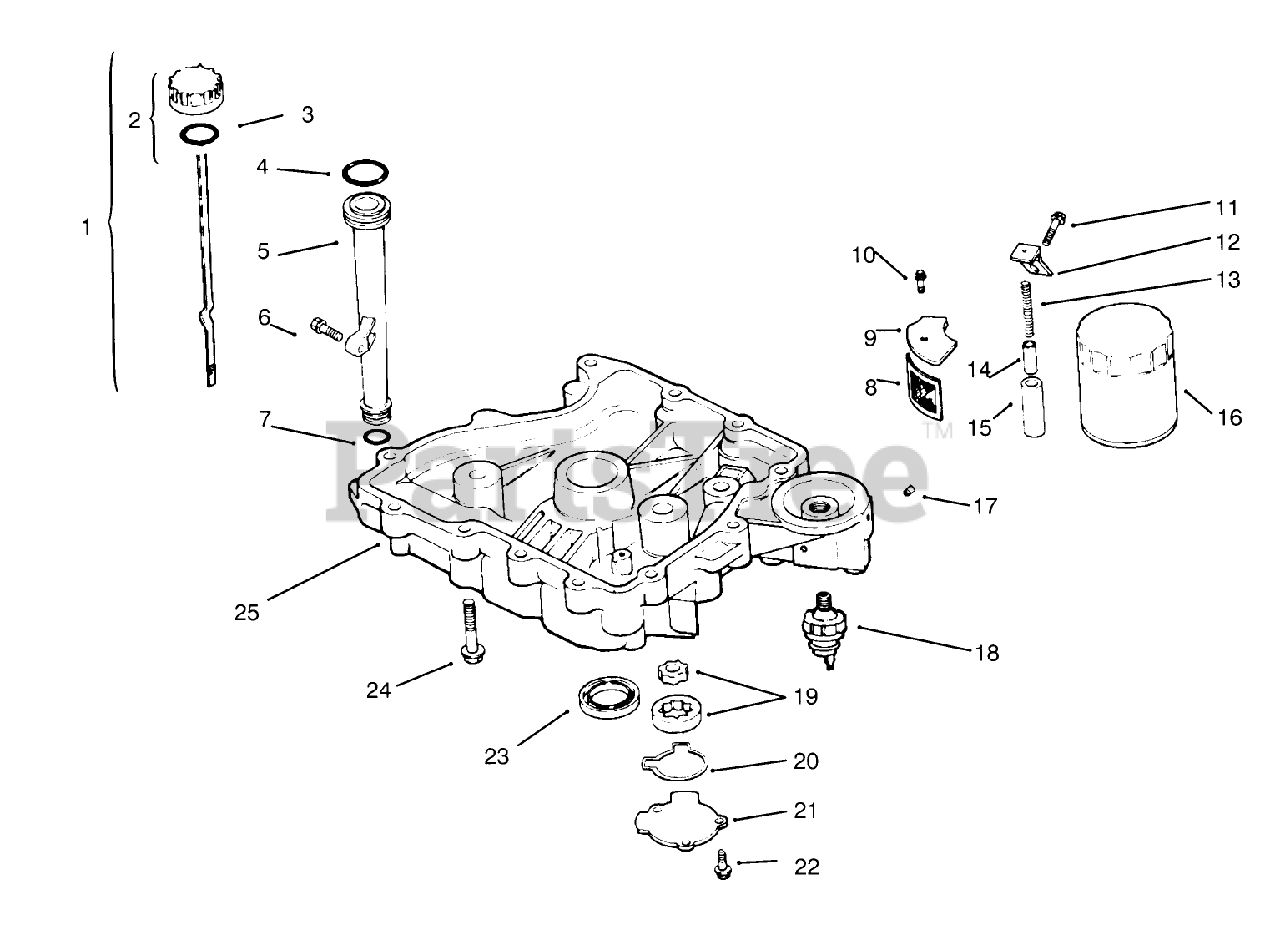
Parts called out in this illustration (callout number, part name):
1	Dipstick INC 2-3 (Only On: 72042, 72063, 72062, 72043)
2	Kit-Oil Fill Cap (Incl. Ref. #7)
3	ORing
4	O Ring-Upper Fill Tube (Only On: 72103)
5	Tube-Oil Fill (Only On: 72103, 72083)
7	O-Ring-Lower Fill Tube (Only On: 72042, 72063, 72062, 72043)
8	Screen-Oil Pickup (Only On: 72042, 72063, 72062, 72043)
9	Cover-Oil Pickup Screen (Only On: 72042, 72063, 72062, 72043)
10	Screw M5x0.8x16 (Only On: 72042, 72063, 72062, 72043)
11	Screw M10x1.5x25 (Only On: 72042, 72063, 72062, 72043)
12	Bracket-Oil Pump Relief (Only On: 72042,72043,72062,72063)
13	Spring-Oil Relief Valve (Only On: 72042,72043,72062,72063)
14	Piston-Oil Relief Valve (Only On: 72042, 72063, 72062, 72043)
15	Body-Oil Relief Valve (Only On: 72042, 72063, 72062, 72043)
16	Filter-Oil
18	Switch-Oil Pressure
19	Pump-Oil (Only On: 72042, 72063, 72062, 72043)
20	O Ring-Oil Pump Cover (Only On: 72042,72043,72062,72063)
21	Cover-Oil Pump (Only On: 72042,72043,72062,72063)
22	Screw M5x0.8x16 (Only On: 72042, 72063, 72062, 72043)
23	Seal-Crankshaft (Only On: 72042, 72043, 72062, 72063)
24	Screw M8x1.25x45 (Only On: 72042, 72063, 72062, 72043)
25	Pan-Oil (Only On: 72042,72043,72062,72063)
